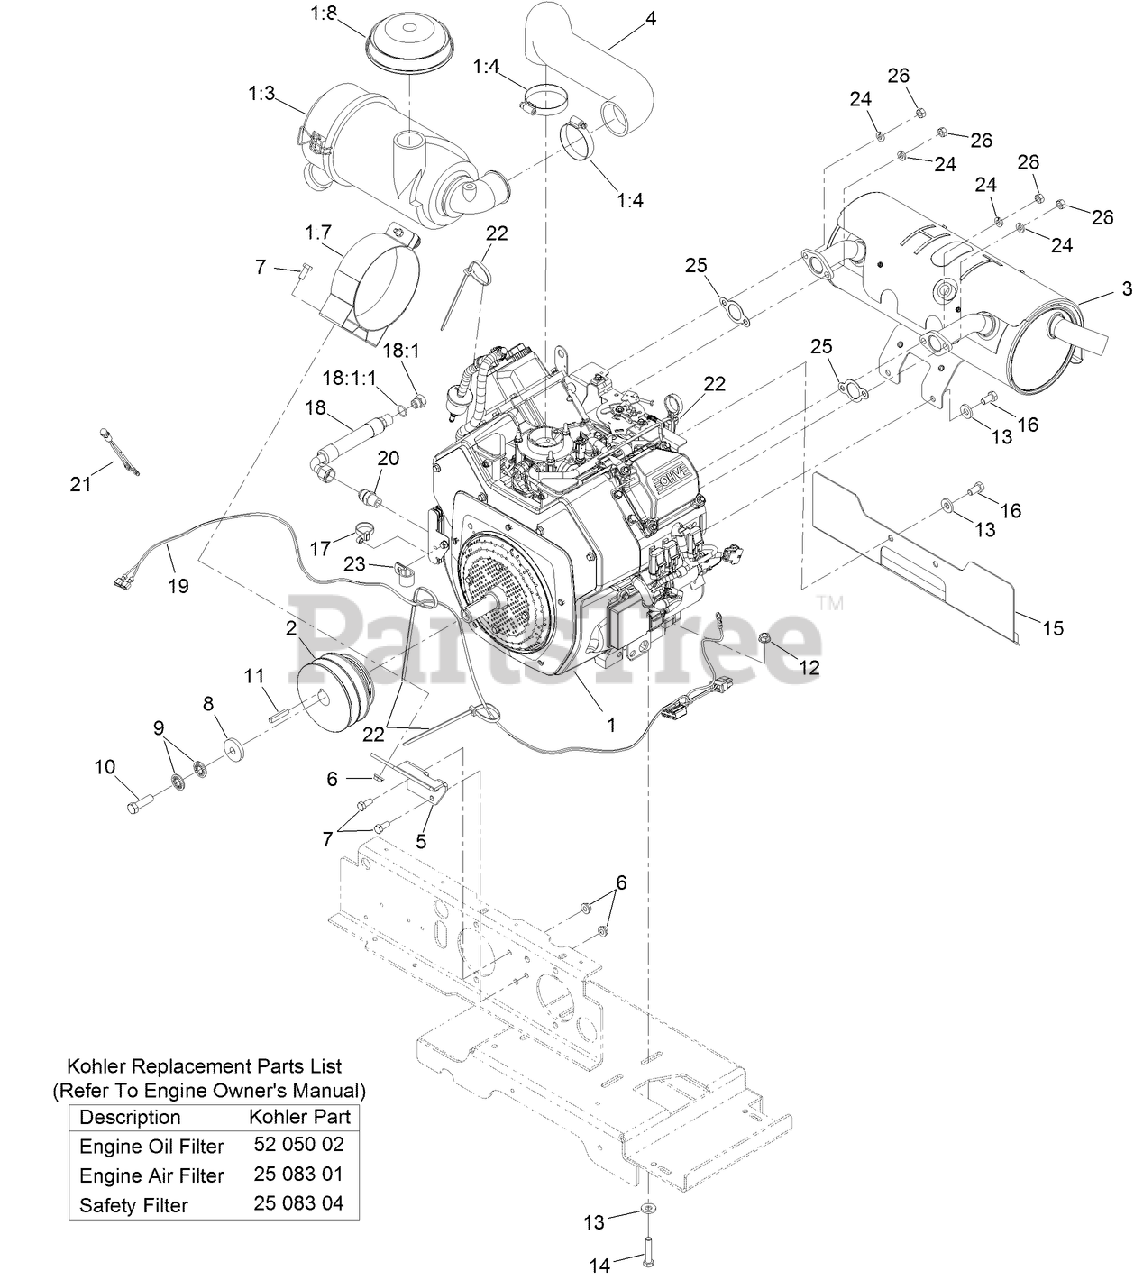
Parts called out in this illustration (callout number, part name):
1:3	AIR CLEANER CANISTER ASM
1:4	CLAMP-HOSE
1:7	BRACKET-FILTER, AIR
1:8	HOOD-CLEANER, 2" AIR INTAKE
2	SHEAVE-ENGINE
3	MUFFLER
4	HOSE-EFI AIR INTAKE
5	BRACKET-FILTER, AIR
6	NUT-HF
7	SCREW-HH
8	WASHER-CLUTCH
9	WASHER-SPRING
11	KEY-SQUARE
12	NUT-HHF, WHIZ
13	WASHER-BELLEVILLE
14	SCREW-HH
15	SHIELD-EXHAUST
16	SCREW-HH
17	TIE-CABLE
18	OIL DRAIN HOSE ASM
18:1	PLUG-HH
18:1:1	O-RING
19	HARNESS-LIGHT INDICATOR (EFI)
20	FITTING-STRAIGHT
21	INDICATOR-LED, RED
22	TIE-PLASTIC
23	CLIP-LOOM
24	WASHER-LOCK
26	NUT-HEX
